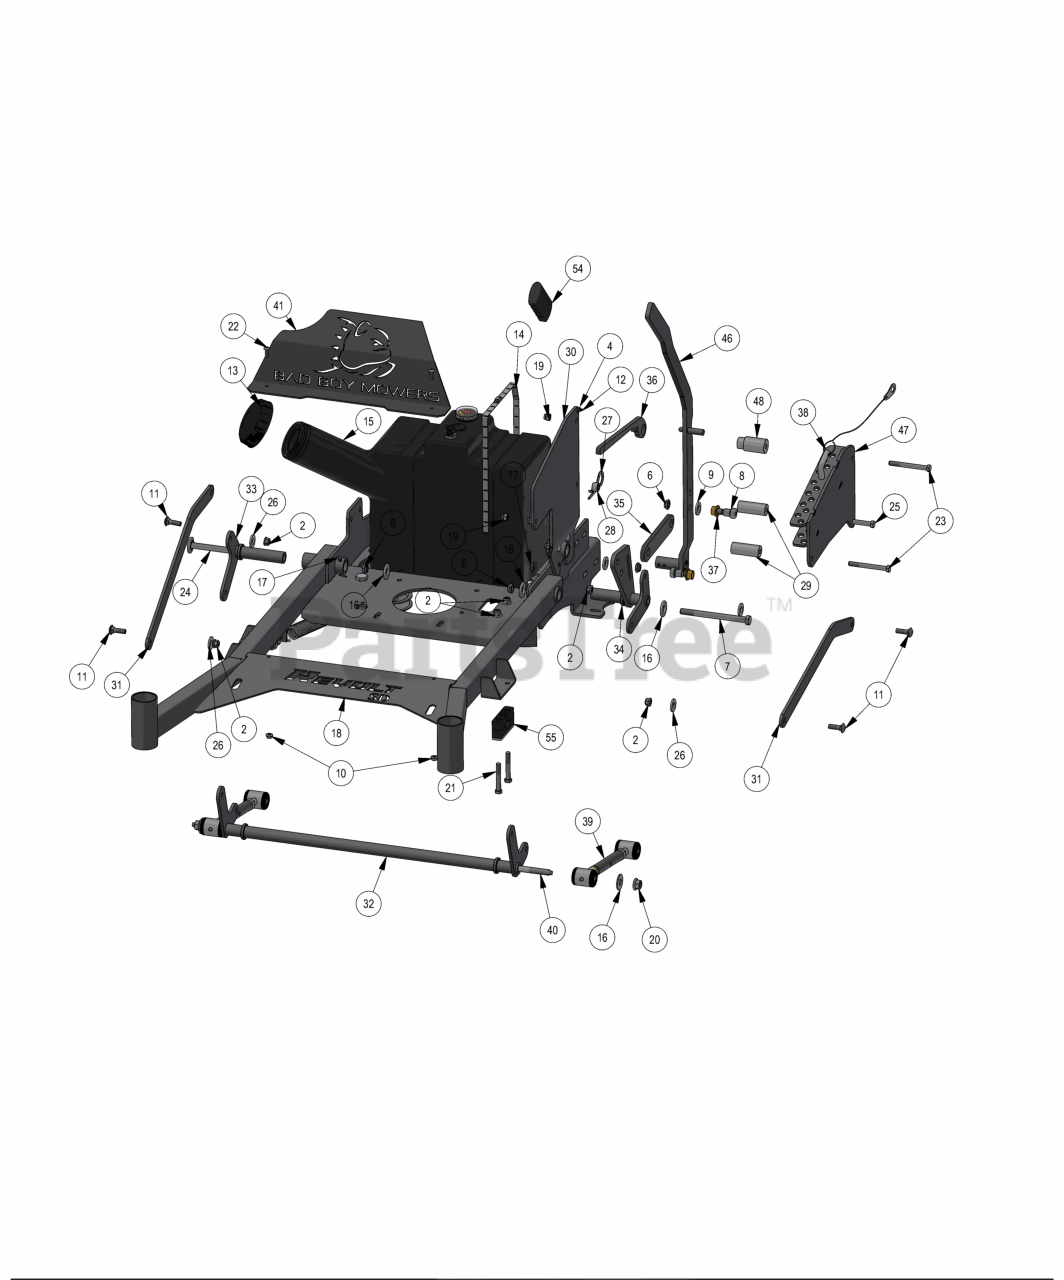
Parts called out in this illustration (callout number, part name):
1	5/16-18 HEX SERRATED FLANGE NUT HARD/ZINC
2	3/8 Nylock Flange Nut
3	5/16-18 NYLON INSERT FLANGE LOCKNUT ZINC
4	10-24 NYLON INSERT LOCKNUT ZINC
5	5/16-18 X 1-1/4 CARRIAGE BOLT ZINC
6	1/2-13 Nylon Insert Jam Locknut
7	1/2-13 X 6 HEX CAP SCREW (GR.5) ZINC
8	5/8 X 5/8 SOCKET SHOULDER BOLT ZINC YELLOW
9	.635 ID X 1.120 OD X .140 THICK FLAT WASHER NYLON
10	1/4-20 NYL INSERT FLANGE LOCKNUT ZINC
11	3/8-16x 1-1/4 Carriage Bolt
12	10-24 X 5/8 BUTTON SOCKET CAP SCREW 18-8 STAINLESS STEEL
14	Tank Strap
15	2019 REVOLT FUEL TANK
16	1/2 Flat Washer
17	1/4 DRIVE-TYPE STRAIGHT GREASE FITTING (NO BALL) ZINC YELLOW
18	2023 Stand On Frame Weldment -SD
19	3/8-16 NYLON INSERT LOCKNUT ZINC
20	1/2-13 NYLON INSERT FLANGE LOCKNUT ZINC
21	3/8-16 x 2 1/2" Hex Bolt
22	1/4"-20 x 3/4 Black Oxide 18-8 Stainless Pan Head
23	3/8-16 X 3-1/2 HEX CAP SCREW (GR.5) ZINC
24	1/2-13 X 5 1/2 HEX CAP SCREW (GR.5) ZINC
25	3/8-16 X 4-1/4 HEX CAP SCREW (GR.5) ZINC
26	.505 Nylon Spacer
27	Revolt Cotter Pin for 7/8" to 1" shank
28	ACS Spacer 3/4x3/8x1/2
29	Stand On Spacer 2.5''
30	2023 SD Inner Adjustment Plate
31	2023 SD-36 Stand-on Actuator Linkage
32	Revolt Front Actuator Bar Weldment - Raw 2020 36" Black
33	Revolt Rear Actuator Bar Weldment RH 2020 36" Black
34	2023 SD Actuator rear_LH
35	2023 lever secondary linkage
36	2019 Stand On Deck Lever Lock
37	.627 ID X .753 OD X .500 LGTH X 1.000 FLG OD X .094 FLG THICK FLANGED BEARING OIL-IMPREG BRNZ
38	2023 stand on Height Adj Pin
39	2018 Maverick Turnbuckle (Top Link)
40	2020 36 Stand On Turnbuckle Rod
41	Exhaust Shield SD
42	1/2-13 HEX NUT ZINC
43	All Thread
44	5/8-11 NYLON INSERT LOCKNUT ZINC
45	Deck spring big diameter
46	2023 Stand On SD Lift Lever Weldment
47	2023 Stand On Outer Adjustment Plate weldment
48	Stand On Spacer 2.5'' With shoulder
49	36 Pump Idler Arm Weldment
50	3.25 Flat Idler Pulley
51	1/2-13 X 2-1/4 HEX CAP SCREW (GR.5) ZINC
52	5/16-18 NYL INS L/N ZC
53	.565 ID X 1.250 OD X .095 THK FLAT WASHER BRASS
54	2019 Stand On Lift Grip
55	Pillow Block Kit
56	1/4 DRIVE-TYPE STRAIGHT GREASE FITTING ZINC YELLOW)
